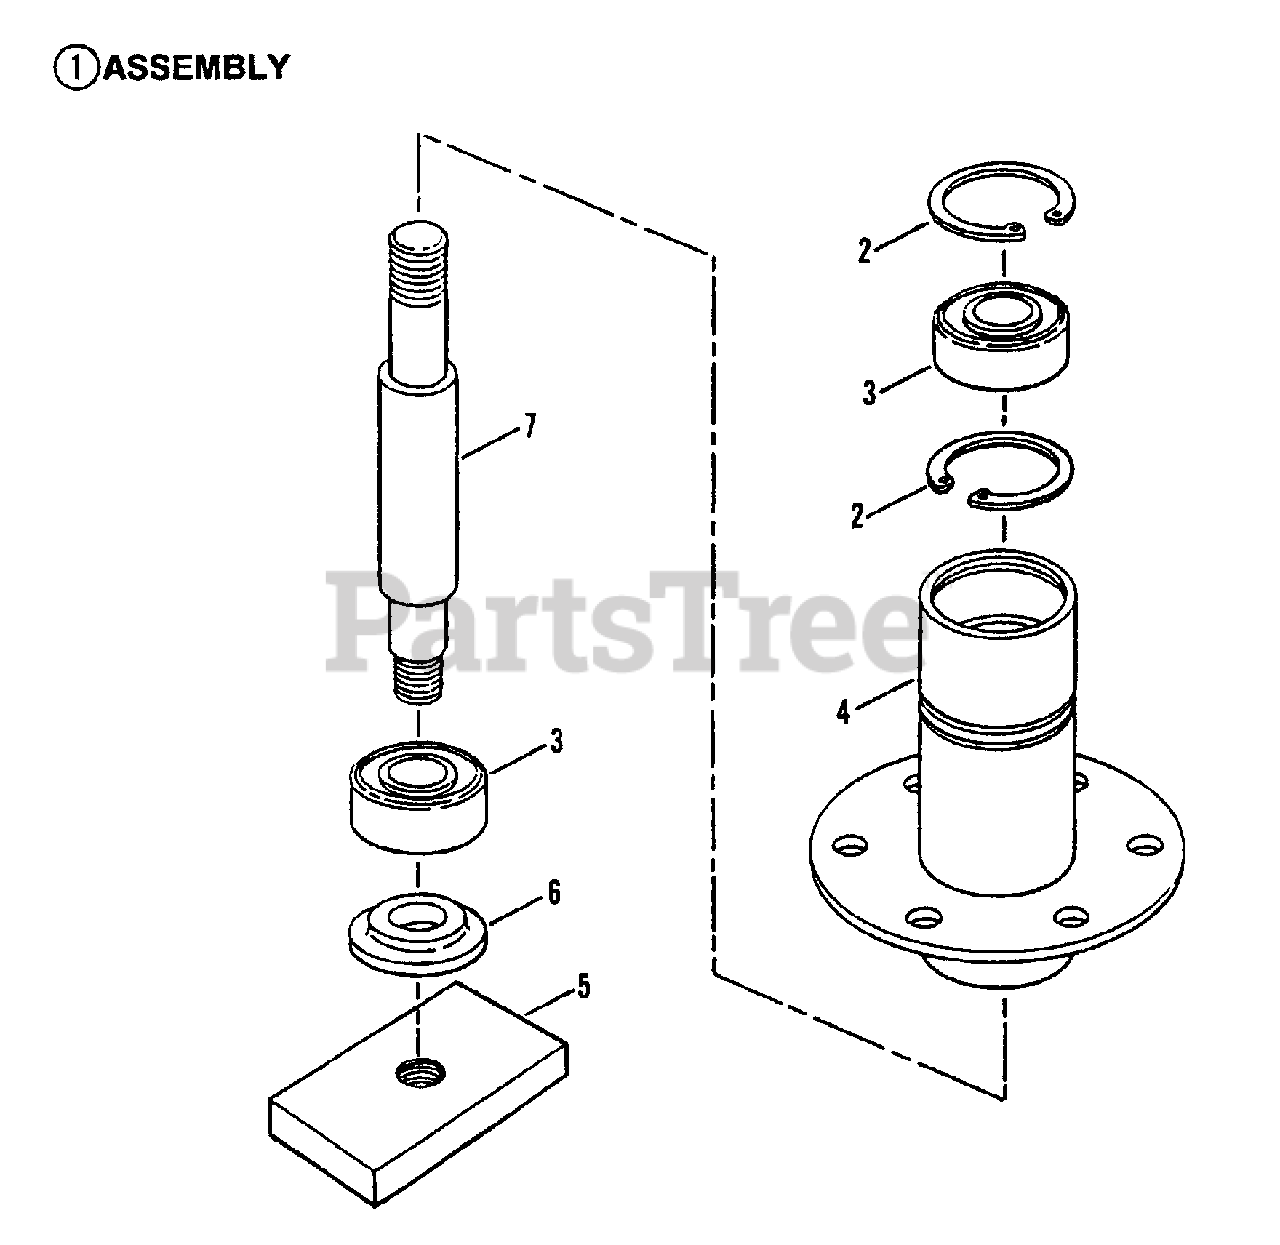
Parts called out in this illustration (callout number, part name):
1	ASSEMBLY, Spindle Housing, 42" Cutting Deck
2	RING, External Retaining 1-3/4"
3	BEARING, Spindle
4	HOUSING, Spindle
5	HOLDER, Blade
6	WASHER, Spindle
7	SPINDLE, 6.5" Long
